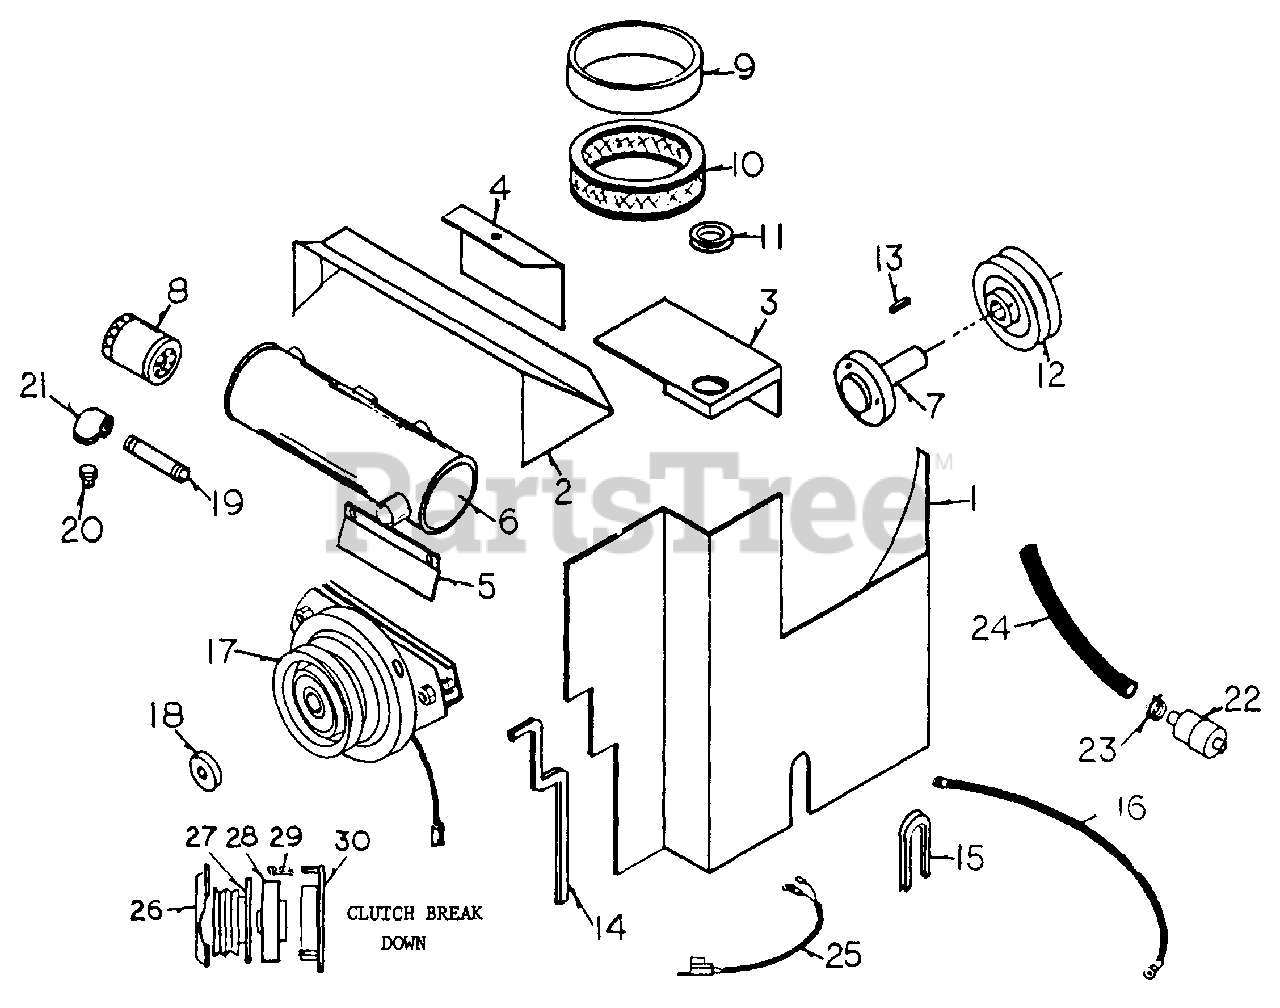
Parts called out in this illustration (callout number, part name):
1	Heat Shield, Part A
2	Heat Shield, Part B
3	Heat Shield, Part C
4	Heat Shield, Part D
6	Muffler (Onan)
7	Engine Shaft (Onan)
8	Oil Filter (Onan)
9	Filter Element (Onan)
10	Filter Cartridge (Onan)
13	Key Stock, 1/4" x 1"
17	Electric Clutch
18	Clutch Retainer Washer
19	Pipe Nipple, 3/8"
20	Pipe Plug, 3/8"
21	Pipe Elbow, 3/8"
22	Fuel Filter
23	Fuel Line Clamp
24	Fuel Line, 38"
25	Starter Harness
27	Clutch Armature
29	Clutch Brake Spring
